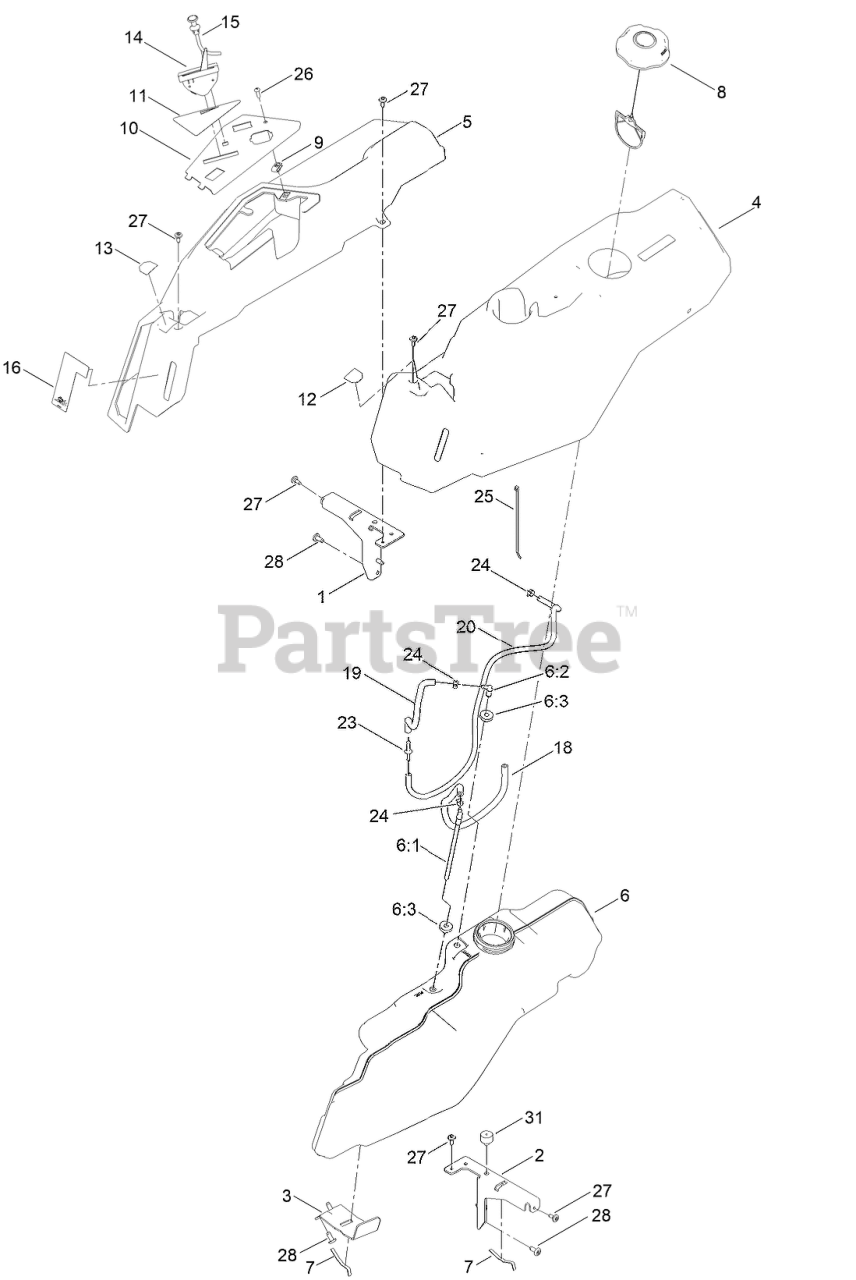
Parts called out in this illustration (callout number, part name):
1	SUPPORT-POD, RH
2	SUPPORT-POD, LH
3	SUPPORT-TANK, FUEL
4	POD-LH
5	POD-RH
6	FUEL TANK ASM
6:1	CONNECTOR-ELBOW, 90 DEG
6:2	FITTING-PLASTIC
6:3	BUSHING
7	SPRING
8	CAP-FUEL, RATCHETING
10	PANEL - CONTROL
11	DECAL-PANEL, CONTROL
12	DECAL-CONTROL LEVER, LH
13	DECAL-CONTROL LEVER, RH
14	CABLE-THROTTLE
15	CABLE-CHOKE
16	DECAL-SMART SPEED
18	HOSE-FUEL
19	HOSE-FUEL
23	ADAPTOR-ORIFICE
24	CLAMP-HOSE
25	TIE-CABLE
26	SCREW-PRH
27	SCREW-SHOULDER
31	BUMPER-GROMMET
